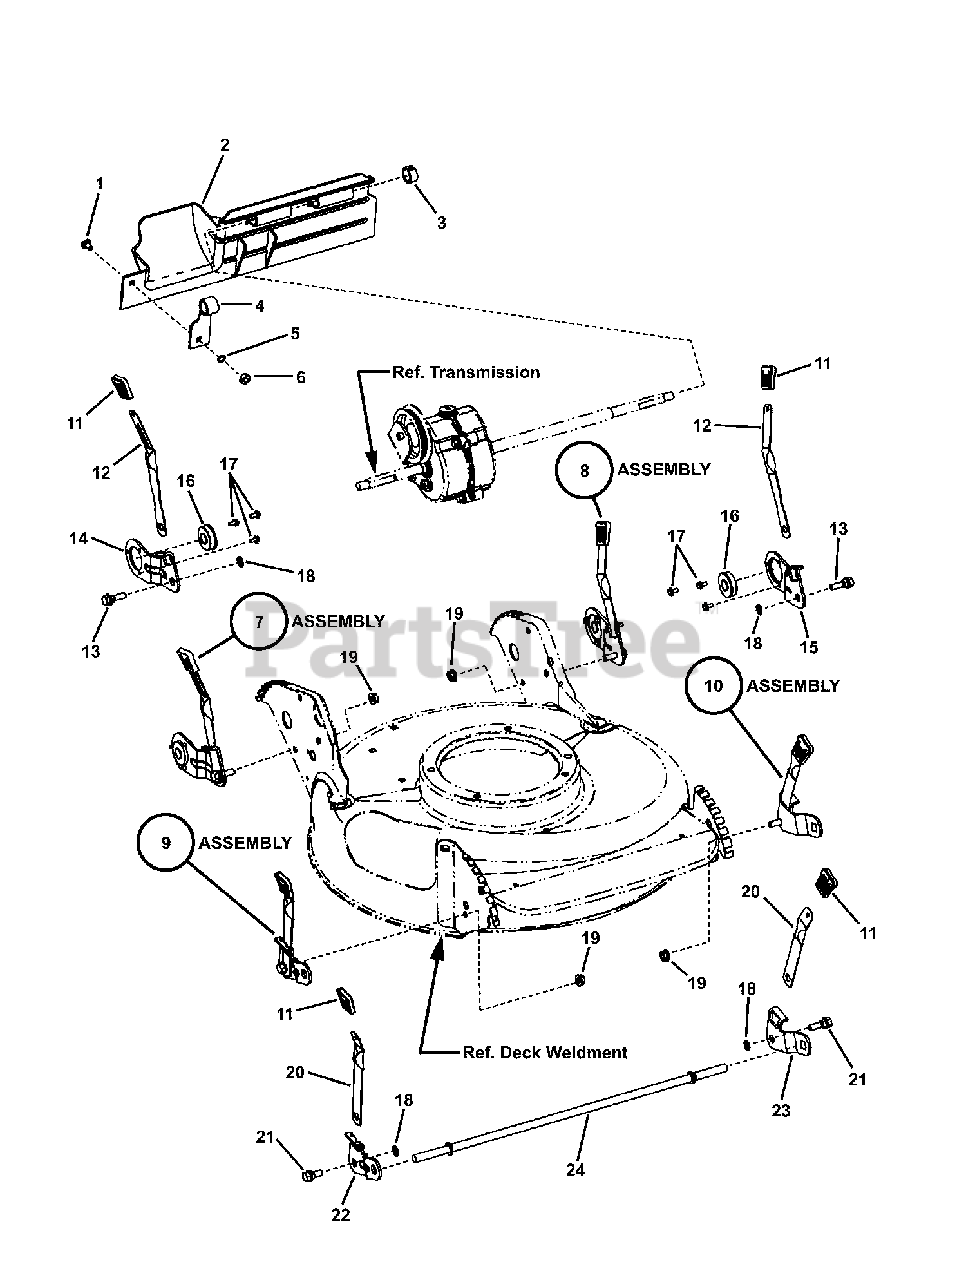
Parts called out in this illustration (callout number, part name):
1	BOLT, 1/4-20 x 1/2" Short Neck Carriage GR 5
2	FOOT GUARD, Rear
3	RING, Split (Black)
4	SUPPORT, Foot Guard
5	WASHER, 1/4" Internal Tooth Lock
6	NUT, 1/4-20 Hex, GR 5 or B
7	ASSY, Wheel Arm, Right Rear (S.P.)
8	ASSY, Wheel Arm Left Rear Long SP21S
9	ASSEMBLY, Right Wheel Arm
10	ASSEMBLY, Left Wheel Arm
11	GRIP, Height Latch - Black (1.3" Wide)
12	LATCH, Height Adjusting (long)
13	BOLT, 5/16-18 x 1" Hex Washer Face Shoulder
14	ARM, Wheel, Right Rear
15	ARM, Wheel, Left Rear
16	BEARING, 9/16" I.D.
17	SCREW, #10-32 x 3/8" Hex Washer Self-Tap
18	RETAINER, 5/16" Bolt
19	NUT, 5/16-18 Hex Flange Lock, GR 5
20	LATCH, Height
21	BOLT, 5/16-18 x 3/4" Hex Washer Face Shoulder
22	WHEEL ARM, R.H. Front (Round Hole)
23	WHEEL ARM, L.H. Front (Square Hole)
24	AXLE, 21"
